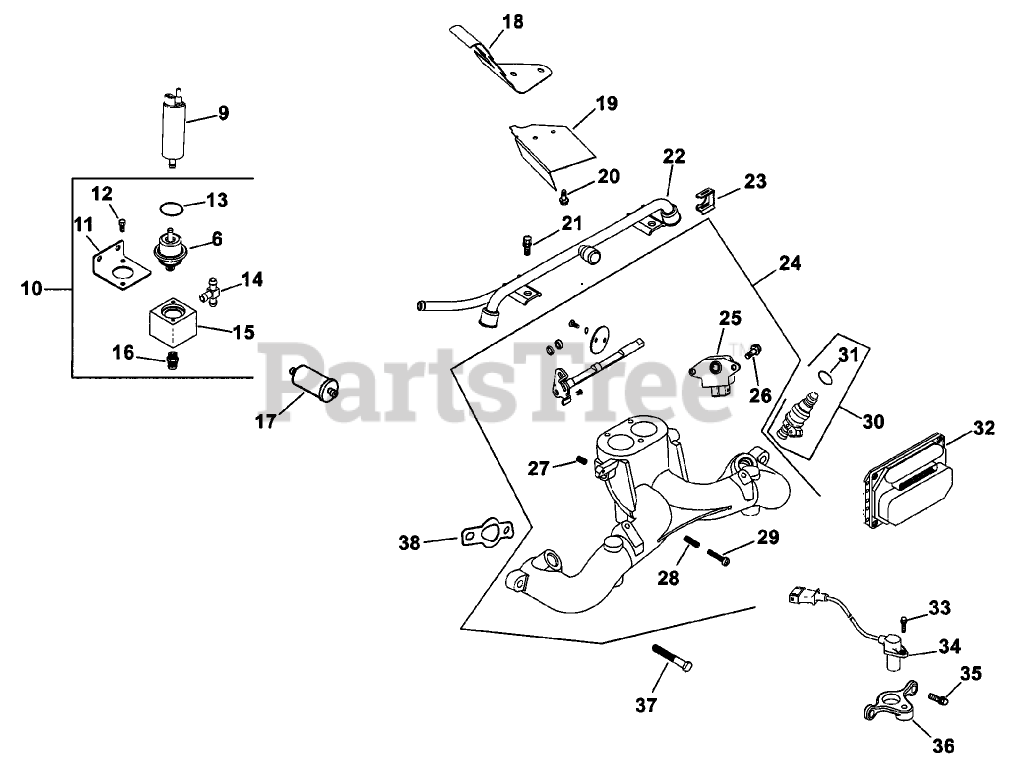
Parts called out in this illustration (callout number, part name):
6	Regulator-Pressure
9	Fuel Pump ASM
10	Pressure RegulatorASM(Incl. Ref.# 6,11-16)
11	Bracket-Regulator,Horizontal
12	Screw-HH
13	O-Ring
14	Fitting-Tee
15	Housing-Regulator,Horizontal
16	Connector-Hose, Straight
17	Filter-Fuel
18	Baffle-Valley
19	Deflector-Air
20	SCREW-HHFTF (M5X.80X10)
21	Screw-HF (M6x1.0x10)
22	Rail-Fuel
23	Clip-Injector, Fuel
24	Intake Manifold ASM(Incl. Ref.#25-29 &24 176 77-S)
25	Sensor-Position,Throttle
26	Screw-Head, Pan
27	Spring, Idle Bump
28	Spring-Control, Speed
29	Screw-HH
30	Injector-Fuel(Incl. Ref.# 31)
31	O-RING
32	Module-Management,Ignition
33	Screw-HF
34	Sensor-Speed, Engine
35	SCREW-FLANGE, THREAD FORMING (M5X0.8X16)
36	Bracket-Sensor,Speed
37	Screw-HF
38	Gasket-Manifold, Intake
